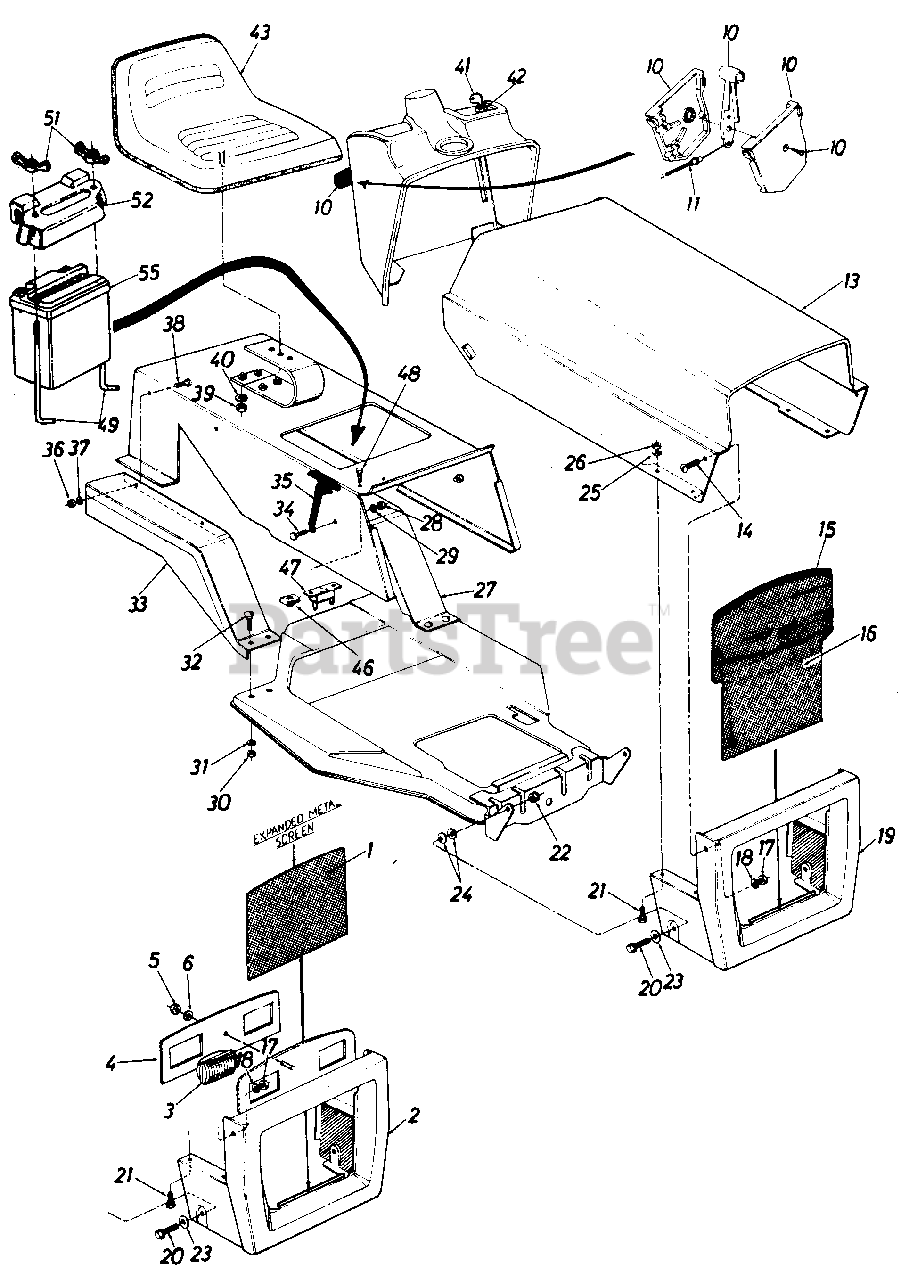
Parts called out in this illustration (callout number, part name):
1	Screen-Grile
2	Grille Ass'y.
3	Head Light
4	Head Light Retainer
5	Hex Nut #10-24 Thd.
6	L-Wash. #10 I.D.
10	Throttle Control Box Ass'y.
11	Throttle Control Wire
13	Hood-Front
14	Truss Hd. Mach. Scr. 1/4-20 x.50" Lg.
15	Extruded"U"-Channel 22.50" Lg.
16	Screen-Grille
17	Hex Nut 1/4-20 Thd.
18	L-Wash. 1/4" Scr.
19	Grille Ass'y.
20	Hex Scr. 3/8-16 x 1.00" Lg.
21	Hex Sems Scr. 1/4-20 x .75" Lg.
22	Hex Cent. L-Nut 3/8-16 Thd.
23	Fl-Wash. .385 I.D. x .620 O.D. x .063
24	Bell-Wash. .400 I.D. x .88 O.D.
25	L-Wash. 1/4" Scr.
26	Hex Nut 1/4-20 Thd.
27	Fender Ass'y. L.H.
28	Hex Nut 1/4-20 Thd.
29	L-Wash. 1/4" Scr.
30	Hex Nut 1/4-20 Thd.
31	L-Wash. 1/4" Scr.
32	Carriage Bolt 1/4-20 x .62" Lg.*
33	Fender Ass'y. R.H.
34	Hex Scr. 1/4-20 x .62" Lg.
35	Hood Lock Ass'y.
36	Hex Nut 10-24 Thd.
37	Wash. #10 Scr. Ext.
38	Truss Hd. Mach. Scr. 10-24 x 62" Lg.
39	Hex Nut 1/2-13 Thd.
40	L-Wash. 1/2" Scr.
41	Ignition Key
42	Ignition Switch
43	Seat Ass'y. w/Safety Switch
46	Speed Nut 10-24
47	Circuit Breaker
48	Truss Hd. Mach. Scr. #10-14 x.62" Lg.
49	Hold Down Rod
51	Wing Nut 1/4-20 Thd.
52	Battery Cover
55	12V Battery
